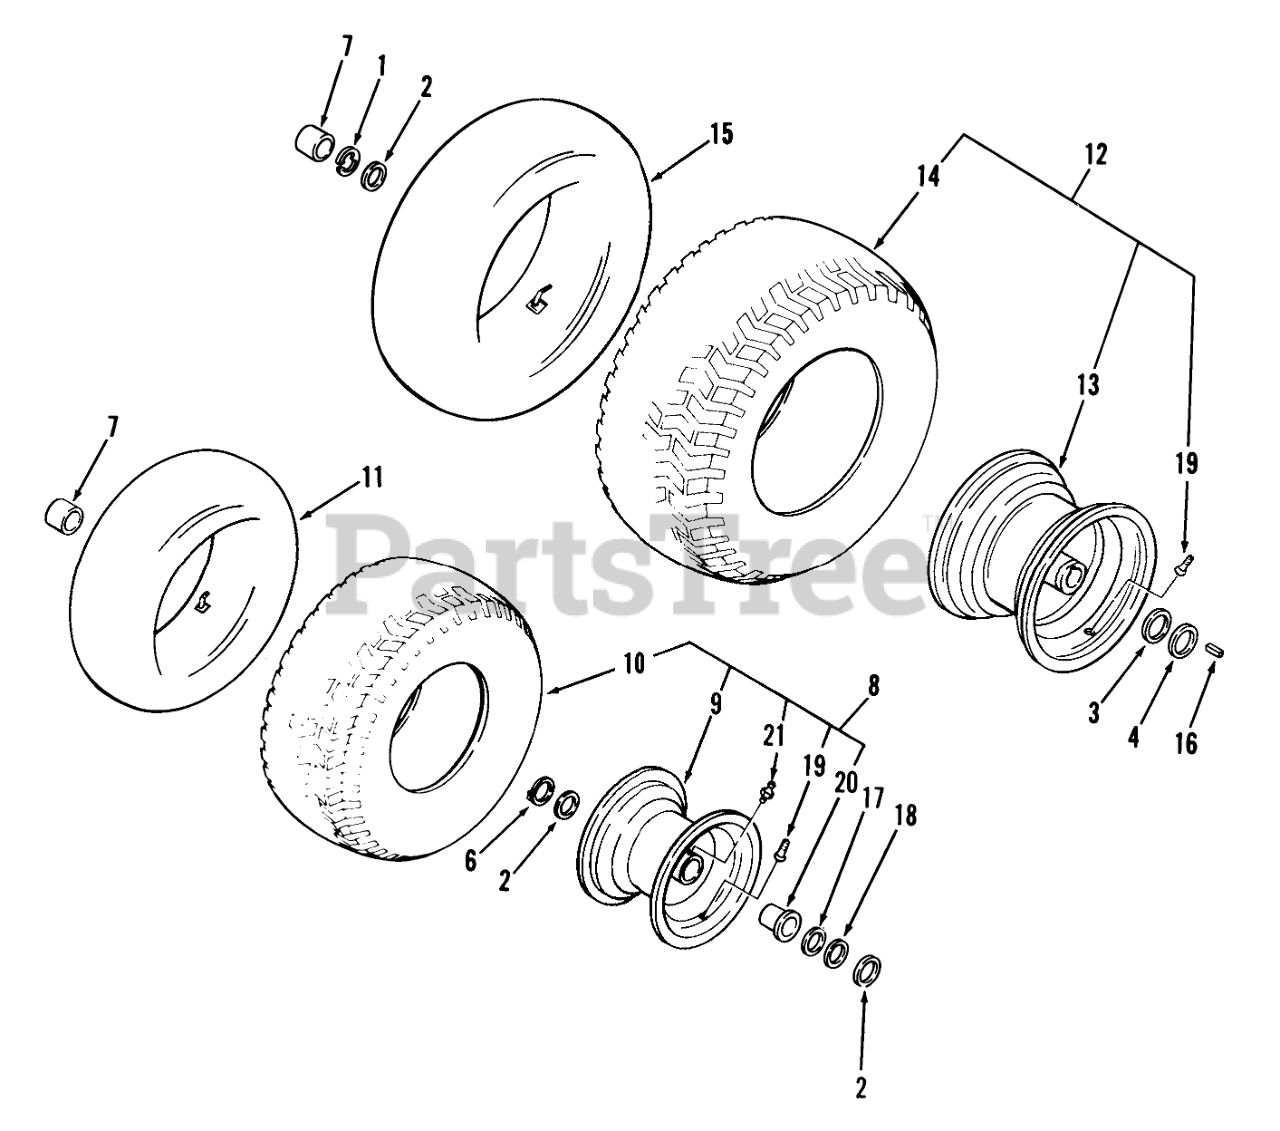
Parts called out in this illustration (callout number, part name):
1	E Ring
2	WASHER-FLAT
3	WASHER-SHIM
4	WASHER
6	Snap Ring
7	HUB CAP
8	Front Wheel
9	Front Wheel (Includes Items 19, 20, 21)
10	TIRE
11	Front Tube-Service Only
12	Assy-Wheel & Tire Rear
13	Rear Wheel
14	TIRE
15	Rear Tube-Service Only
16	SQ KEY
17	WASHER
18	WASHER-SHIM
19	VALVE
20	FLANGE BEARING
21	ZERK-GREASE
